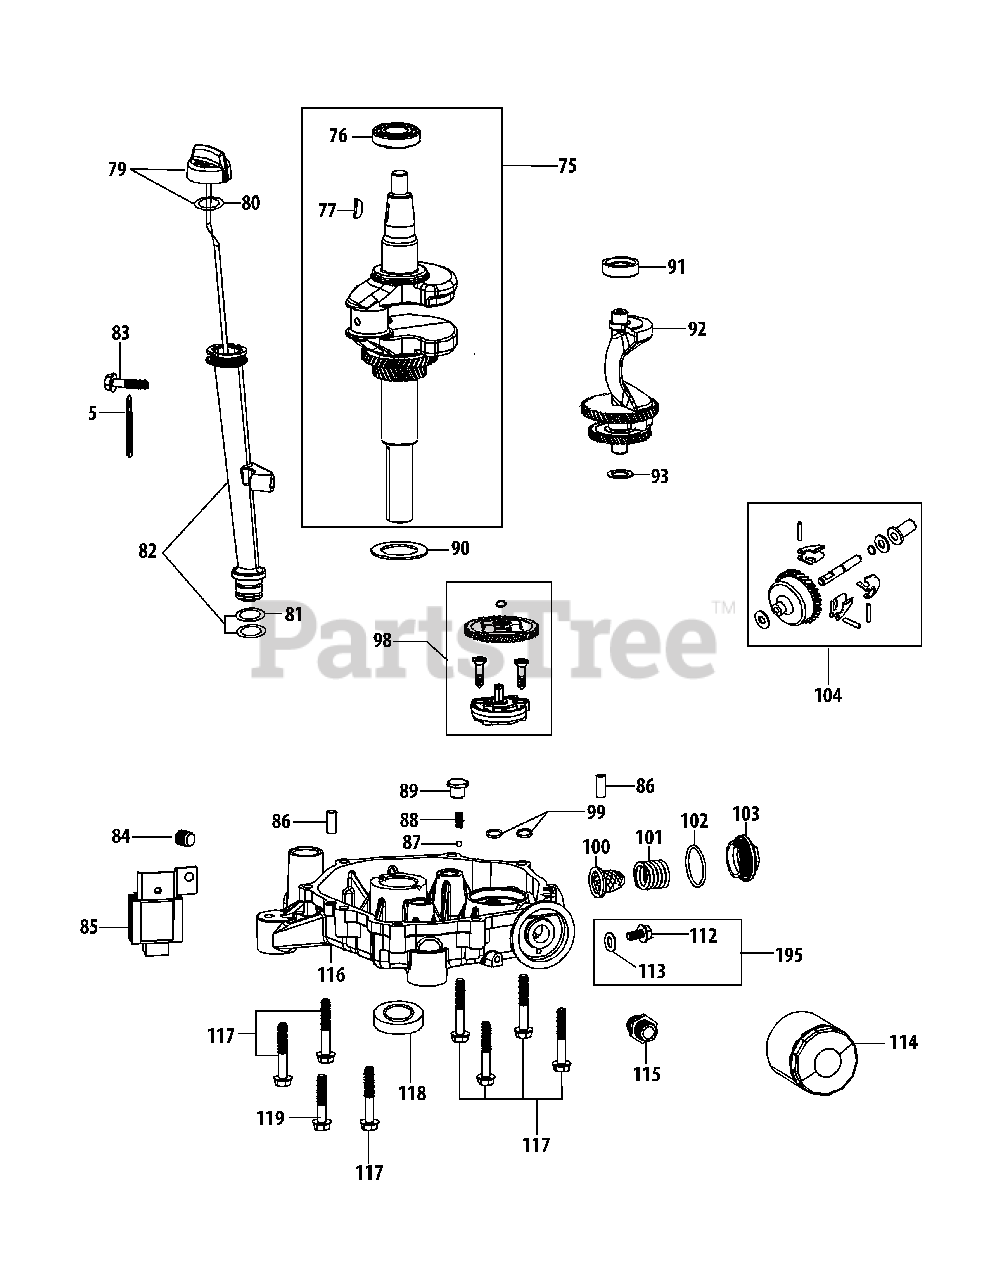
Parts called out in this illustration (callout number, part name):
5	Flexible Clamp
75	Crankshaft Assembly
76	Main Bearing
77	Woodruff Key
79	Dipstick Assembly
80	Upper O-Ring
81	Lower O-Ring
82	Oil Fill Tube Assembly
83	Bolt M6×35
84	Oil Drain Plug
85	Regulator
86	Dowel Pin 8×14
87	Ball 6.35
88	Spring
90	Crankshaft Thrust Washer
91	Balanceable Shaft Bearing
92	Balanceable Shaft Assembly
93	Balanceable Thrust Washer
98	Oil Pump Assembly
99	O-Ring 10×2.65
100	Filter
101	Filter Spring
102	O-Ring 35.5×2.65
103	Filter Cover
104	Governor Gear/Shaft Assembly
112	Bolt M8×15
113	Oil Drain Plug Washer
114	Oil Filter
115	Screw Joint
116	Crankcase Cover
116	Crankcase Cover Asm
117	Bolt M8×54
118	Lower Crankshaft Seal
119	Bolt M8×43
195	Oil Drain Plug Assembly
